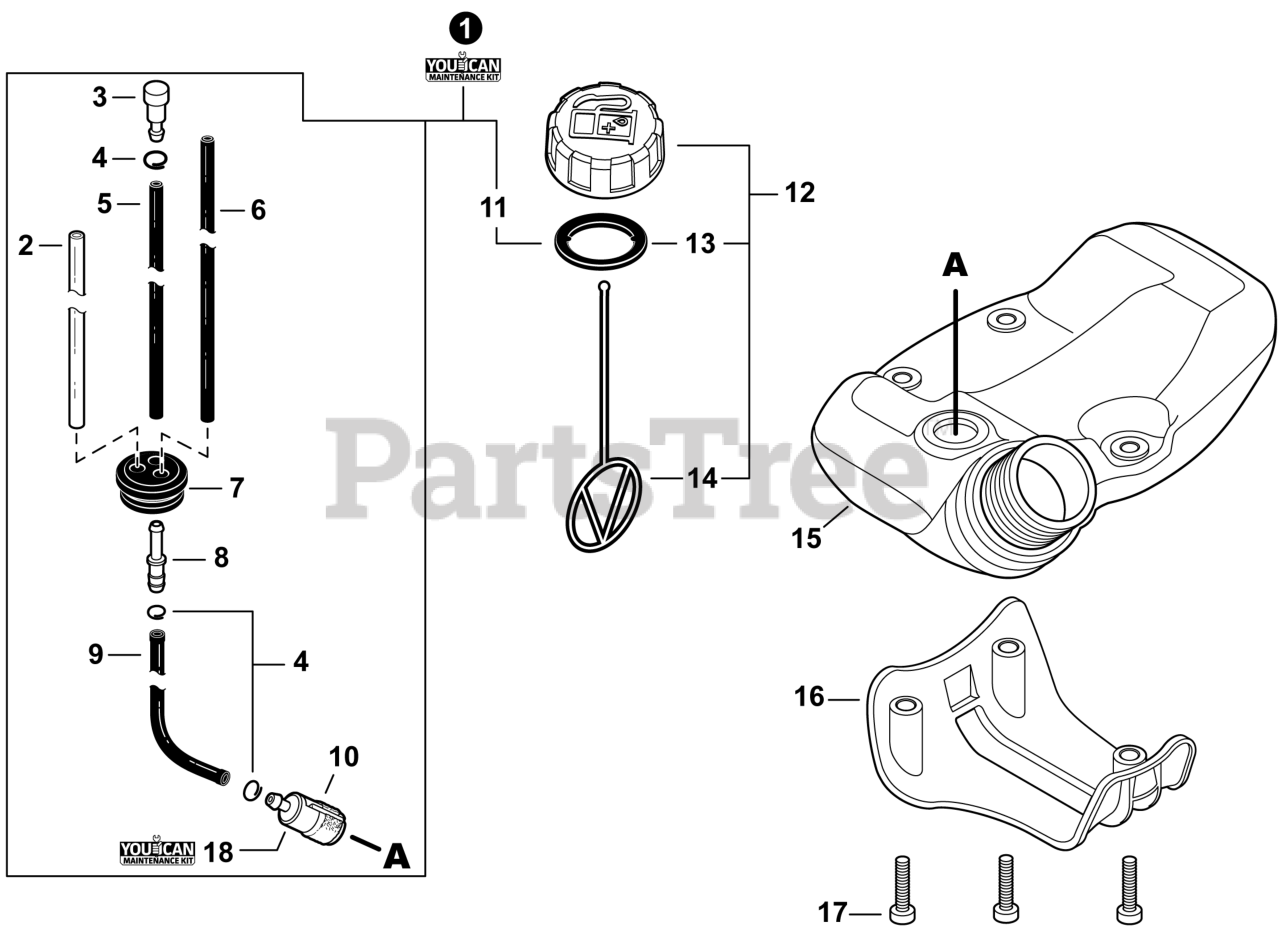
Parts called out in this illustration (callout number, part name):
1	FUEL SYSTEM KIT - YOUCANT
2	PIPE, FUEL 3x6x80 YELLOW
3	VENT ASSY
5	PIPE, FUEL 3x5x90 BLACK
6	PIPE, FUEL 3x5.5x74 BLACK
7	GROMMET, FUEL 5
8	CONNECTOR, PIPE 5x3.5
9	PIPE, FUEL 3x5x130 BLACK
10	FILTER, FUEL
11	GASKET, FUEL CAP
12	CAP ASSY, FUEL
13	GASKET, FUEL CAP
14	CONNECTOR, CAP L= 123
15	TANK, FUEL
16	GUARD, FUEL TANK
17	BOLT, TORX 5x20
18	TUNE-UP KIT - YOUCANT
